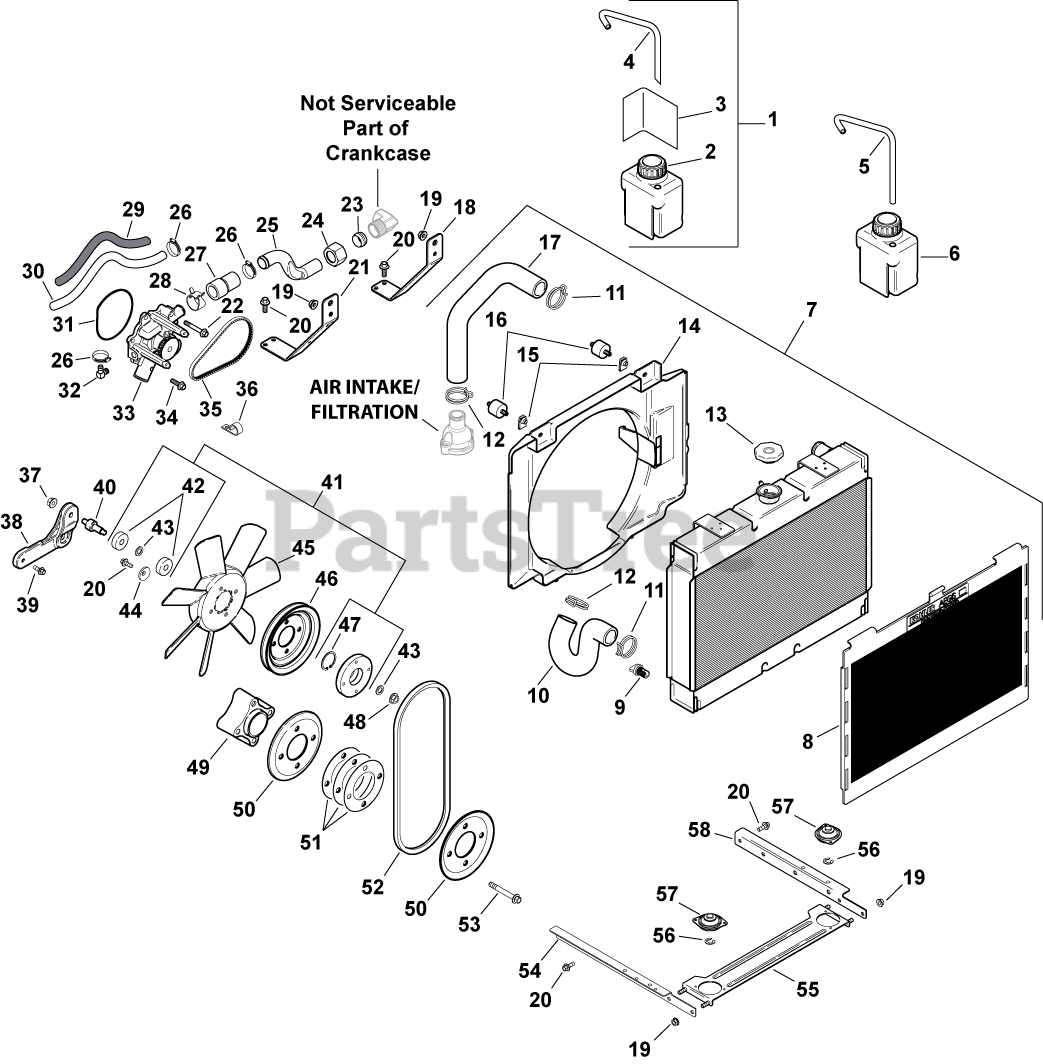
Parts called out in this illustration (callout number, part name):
1	KIT, OVERFLOW BOTTLE
2	DECAL, COOLANT LEVEL
3	CAP, OVERFLOW
4	HOSE, OVERFLOW
7	RADIATOR ASSEMBLY
8	SCREEN, GRASS (FLAT)
10	HOSE, RADIATOR TO WATER PUMP (LOWER)
12	CLAMP, THERMOSTAT HSG OUTLET
13	CAP, RADIATOR
17	HOSE, THERMOSTAT TO RADIATOR (UPPER)
18	BRACKET,UPPER RADIATOR #1 SIDE
19	NUT, FLG M6X1.0
20	SCREW, FLG M6X1.0X16
21	BRACKET, UPPER RADIATOR #2 SIDE
22	SCREW, FLG M6X1.0X40
25	TUBE, CROSSOVER (METAL)
26	CLAMP, HOSE-USE 25 237 32-S
27	TUBE, CROSSOVER (RUBBER)
29	SLEEVE, INSULATING 14"
30	HOSE, BY-PASS 13"
32	CONNECTOR
33	PUMP ASSEMBLY, WATER - USE 66 393 10-S
34	SCREW, FLG M6x1.0x20
35	BELT, WATER PUMP
36	CLIP, CABLE
37	NUT, FLG M8X1.25
38	BRACKET, FAN
39	SCREW, FLG 8X1.25X16
40	KIT, FAN SHAFT
41	KIT, BEARING CARRIER
42	BEARING, BALL
44	WASHER, SPRING 1/4"
45	FAN, AXIAL PULLER
46	PULLEY, FAN
47	RING, RETAINER-INTL O.D. 30MM
48	NUT, FLG M8X1.25
49	ADAPTER, CRANKSHAFT PULLEY
50	PULLEY, CRANKSHAFT
51	SHIM, CRANKSHAFT PULLEY
52	BELT, FAN
53	SCREW, FLG M8X1.25X60
54	BRCKT KIT, LWR RADIATOR #2
55	BRACKET, RADIATOR CROSS
56	RETAINER, E-CLIP
57	MOUNT, PLATEFORM
58	BRCKT KIT, LWR RADIATOR #1
